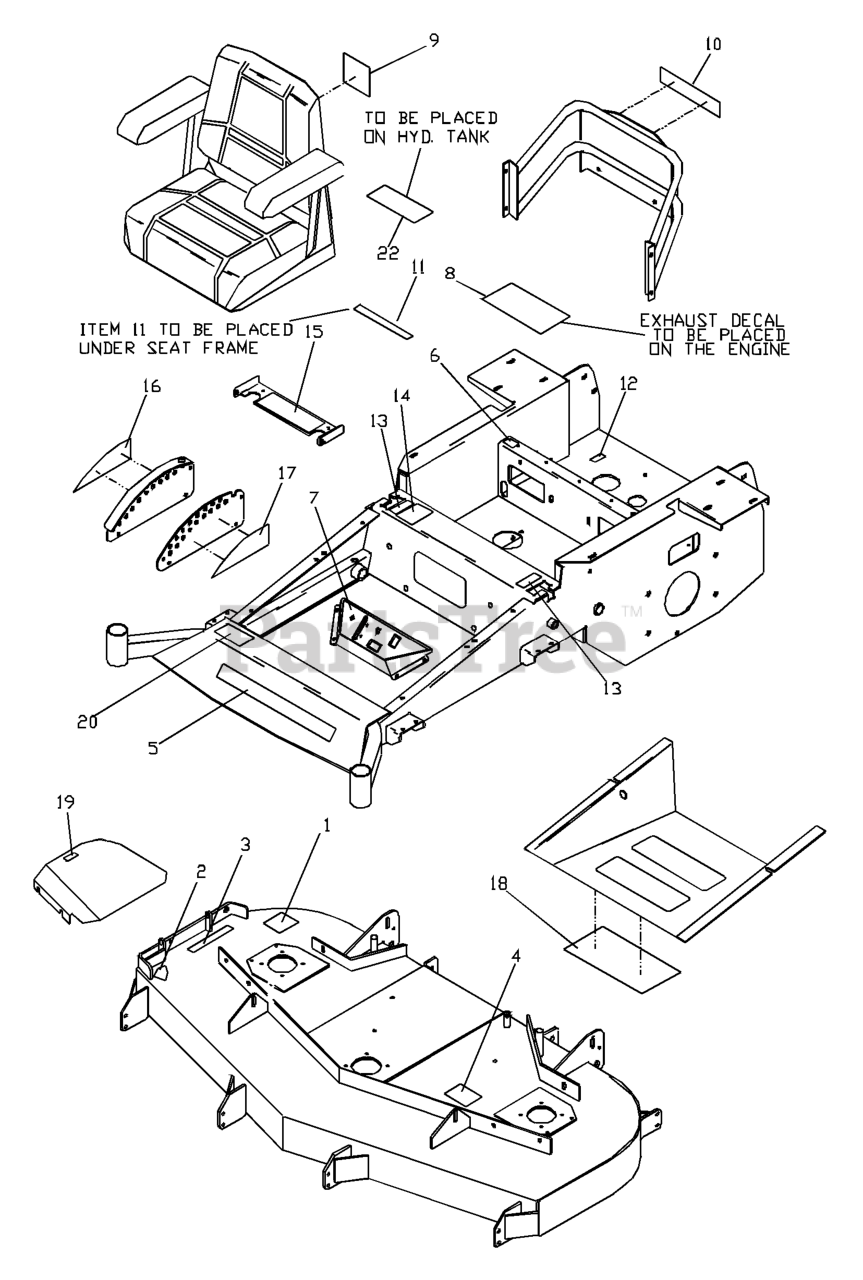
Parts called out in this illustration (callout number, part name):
1	DECAL, ANTI SCALP
2	DECAL, DANGER
3	DECAL, CPSC
4	DECAL, BELT ROUTING
5	DECAL, HUSQVARNA 17.5"
6	DECAL, FUEL VALVE
7	DECAL, CONSOLE
8	DECAL, EXHAUST
9	DECAL, CROWN H
10	DECAL, HUSQVARNA LOGO 9.25"
11	DECAL, BATTERY
12	DECAL, PROP. 65
13	DECAL, MOTION CONTROL
14	DECAL,THROWN OBJECT
15	DECAL, WARNING
16	DECAL, HEIGHT
17	DECAL, HEIGHT
18	DECAL, SERVICE
19	DECAL, NO STEP
20	DECAL, NASCAR
21	DECAL, 5223
21	DECAL 5223L
21	DECAL 5225
21	DECAL 6125
22	DECAL, MOBIL 1
